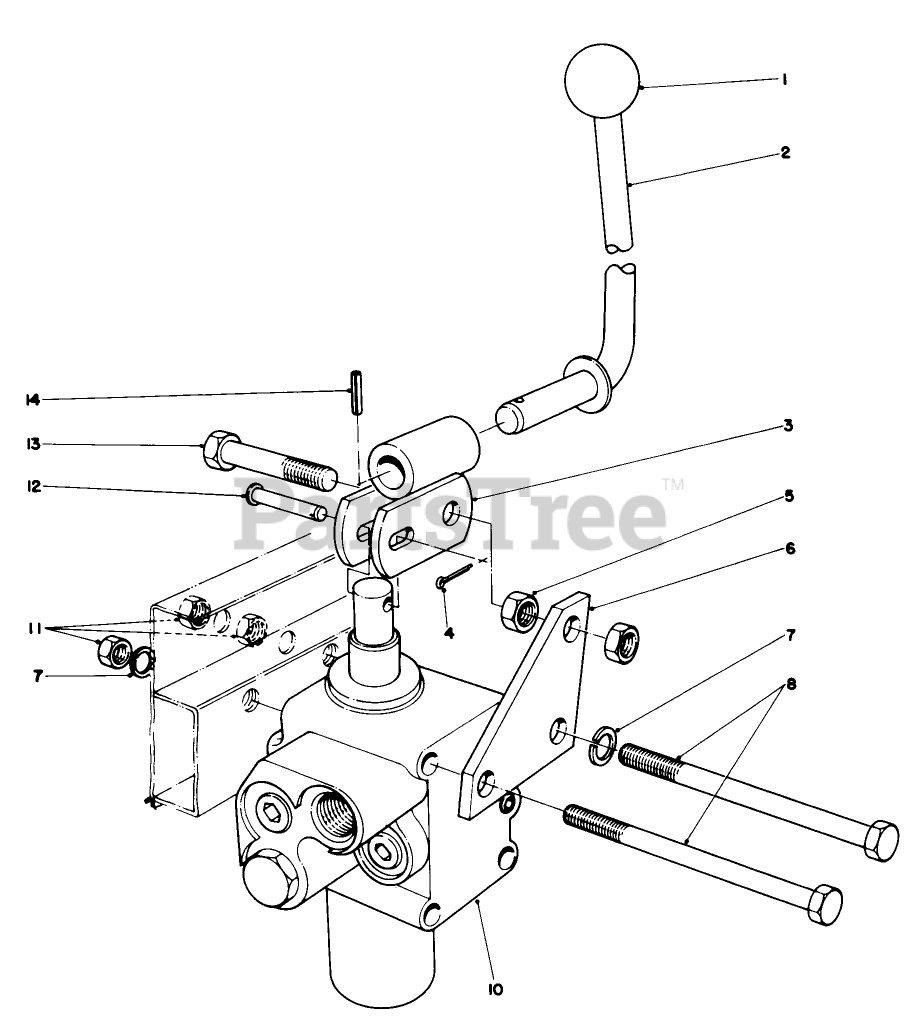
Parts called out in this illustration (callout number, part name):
1	KNOB-CONTROL
2	Valve Lever
4	PIN-COTTER
5	NUT-JAM
6	Bolt-Wheel
7	WASHER-LOCK
8	SCREW-HH
11	NUT-HEX
12	PIN-CLEVIS
13	SCREW-HH
14	PIN-ROLL
